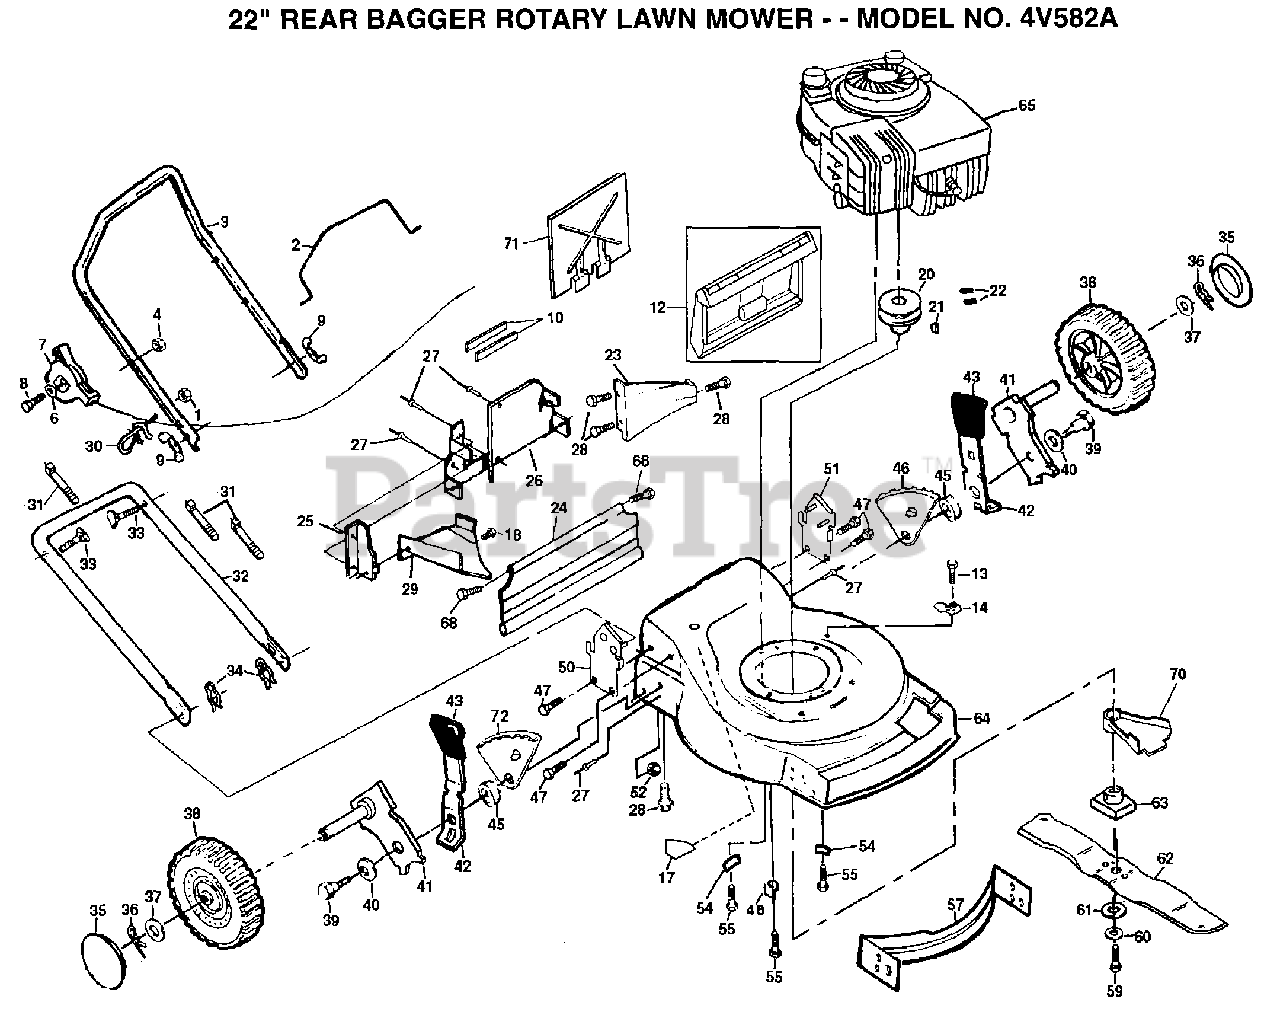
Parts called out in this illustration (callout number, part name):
1	NUT
2	BAIL.CONTROL.BLK.
3	"HANDLE,UPPER"
6	WASHER PM
7	CONTROL.THRT.45.6
8	SCREW.1/4-20X3.00
9	"NUT,WING PM"
10	"SEAL,REAR DOOR"
13	TAPPING SCREW
14	GUIDE CLIP PM
17	DECAL HYT
18	SCREW PM
20	ENGINE PULLEY PM
21	HI PRO KEY PM
22	SCREW
23	REAR BAFFLE
26	PLATE.BACK.22RD
27	BLIND RIVET
28	SCREW
29	DISCHARGE BAFFLE
30	ROPE GUIDE
33	BOLT.HANDLE.LM
34	HAIRPIN COTTER
35	HUB CAP
36	RETAINER CLIP PM
37	WASHER
40	"WASHER, BELLEVIL."
41	AXLE ARM
42	SPRING SELECTOR
43	KNOB PM
47	SCREW
48	DEBRIS SHLD RET
52	LOCKNUT PM
55	SCREW
59	SCREW
60	LOCKWASHER
61	"WASHER,HARDEN"
63	ADAPTOR.BLADE.LM
64	KIT.HSG.22RD.FWGD
68	HINGE SCREW
71	MULCHER PLATE
